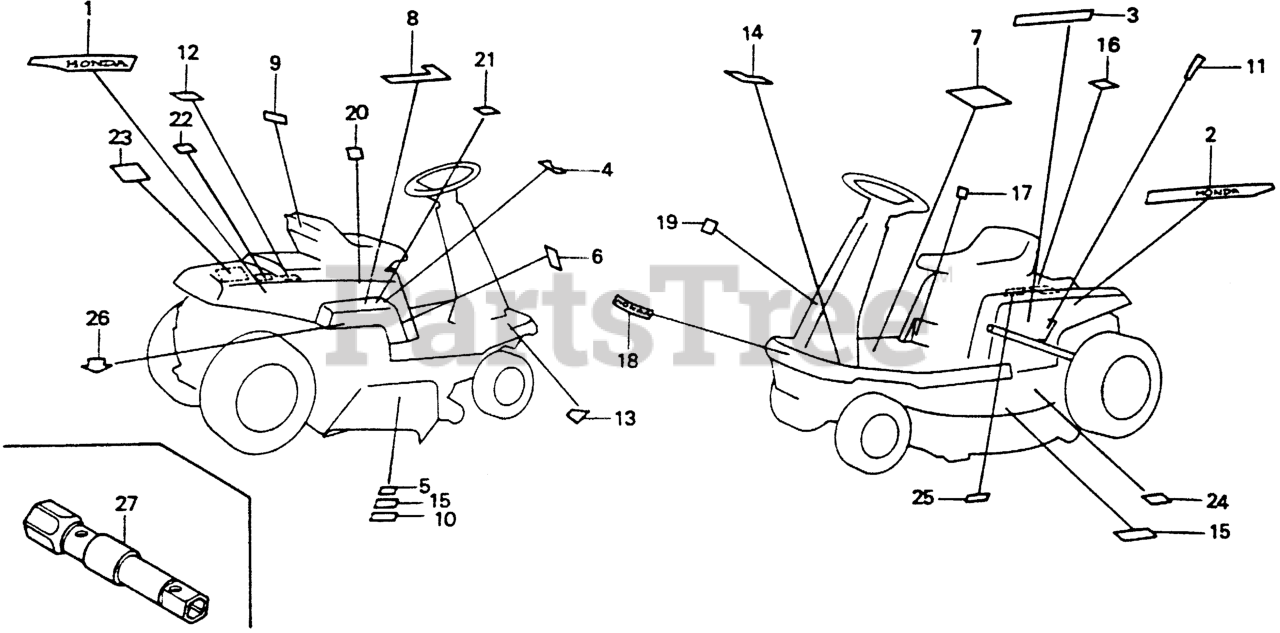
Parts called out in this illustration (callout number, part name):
1	STRIPE, R. SIDE
2	STRIPE, L. SIDE
2	STRIPE, L. SIDE (NOT AVAILABLE)
5	MARK, INCH SIZE (30)
6	MARK, THROTTLE (ENGLISH) (NOT AVAILABLE)
7	LABEL, OPERATION (ENGLISH)
8	MARK, GEAR POSITION (ENGLISH)
9	MARK, SEAT
10	LABEL B, WARNING (ENGLISH)
11	MARK, INDICATOR (ENGLISH)
12	LABEL, MAIN FUSE (ENGLISH) (NOT AVAILABLE)
13	LABEL, BRAKE
14	MARK, P.T.O. CLUTCH (ENGLISH)
15	LABEL A, WARNING (ENGLISH)
16	LABEL, FUEL WARNING (B)
17	MARK, PARKING BRAKE (ENGLISH)
18	MARK, FR. (NOT AVAILABLE)
19	MARK, EMBLEM
21	LABEL, PARKING BRAKE (ENGLISH)
24	LABEL D, CAUTION (ENGLISH)
25	LABEL, AIR CLEANER CAUTION (ENGLISH)
26	MARK, EX. CAUTION (DUTCH)
27	WRENCH, BOX (P21X12)
